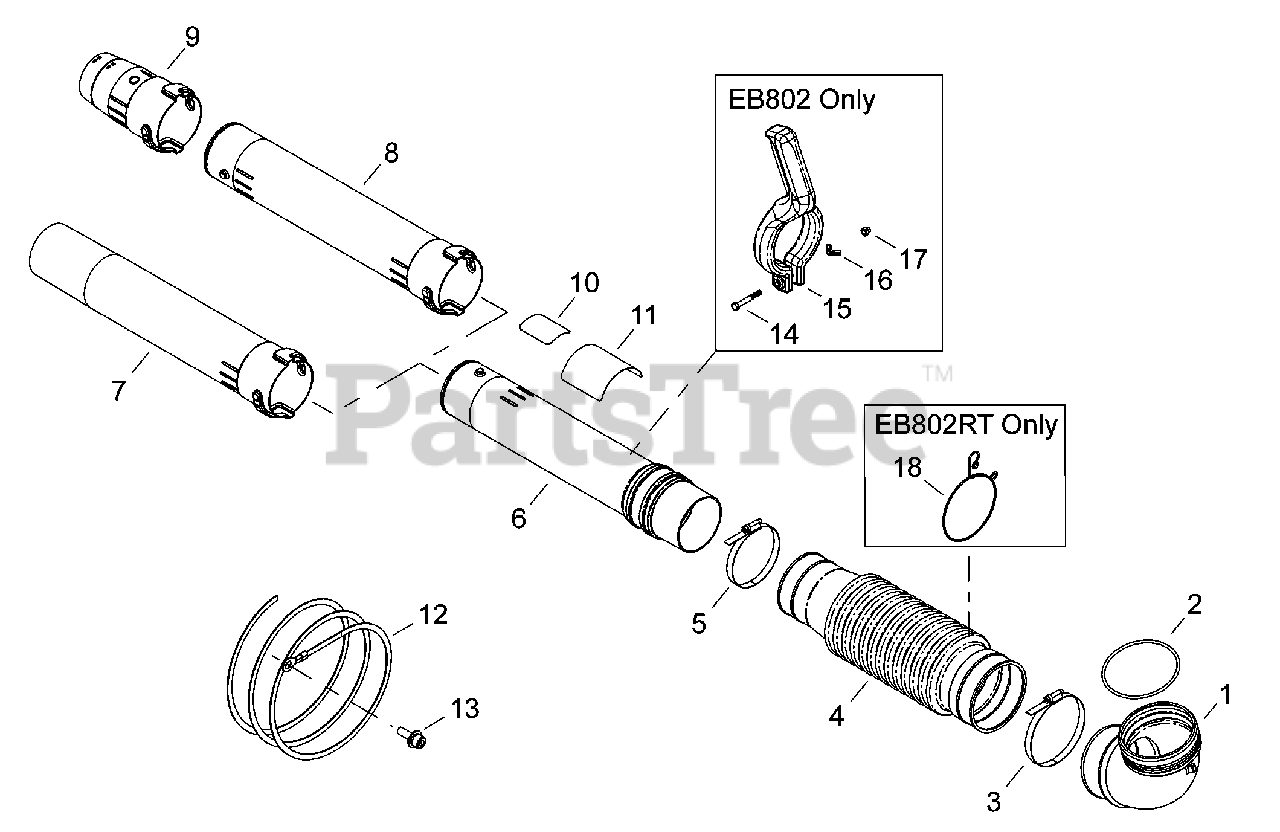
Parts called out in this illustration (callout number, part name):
1	TUBE, BLOWER - ELBOW
2	O-RING
3	CLAMP
4	FLEXIBLE TUBE
5	CLAMP
6	TUBE, BLOWER - SWIVEL
7	NOZZLE - 74mm
8	TUBE, EXTENSION
9	NOZZLE - 65mm
10	LABEL - CAUTION
11	LABEL - SHINDAIWA PROFESSIONAL
12	LEAD - ANTI-STATIC
13	SCREW - 5X16
14	BOLT - 6X60
15	HANDLE
16	WINGNUT
17	NUT - 6
